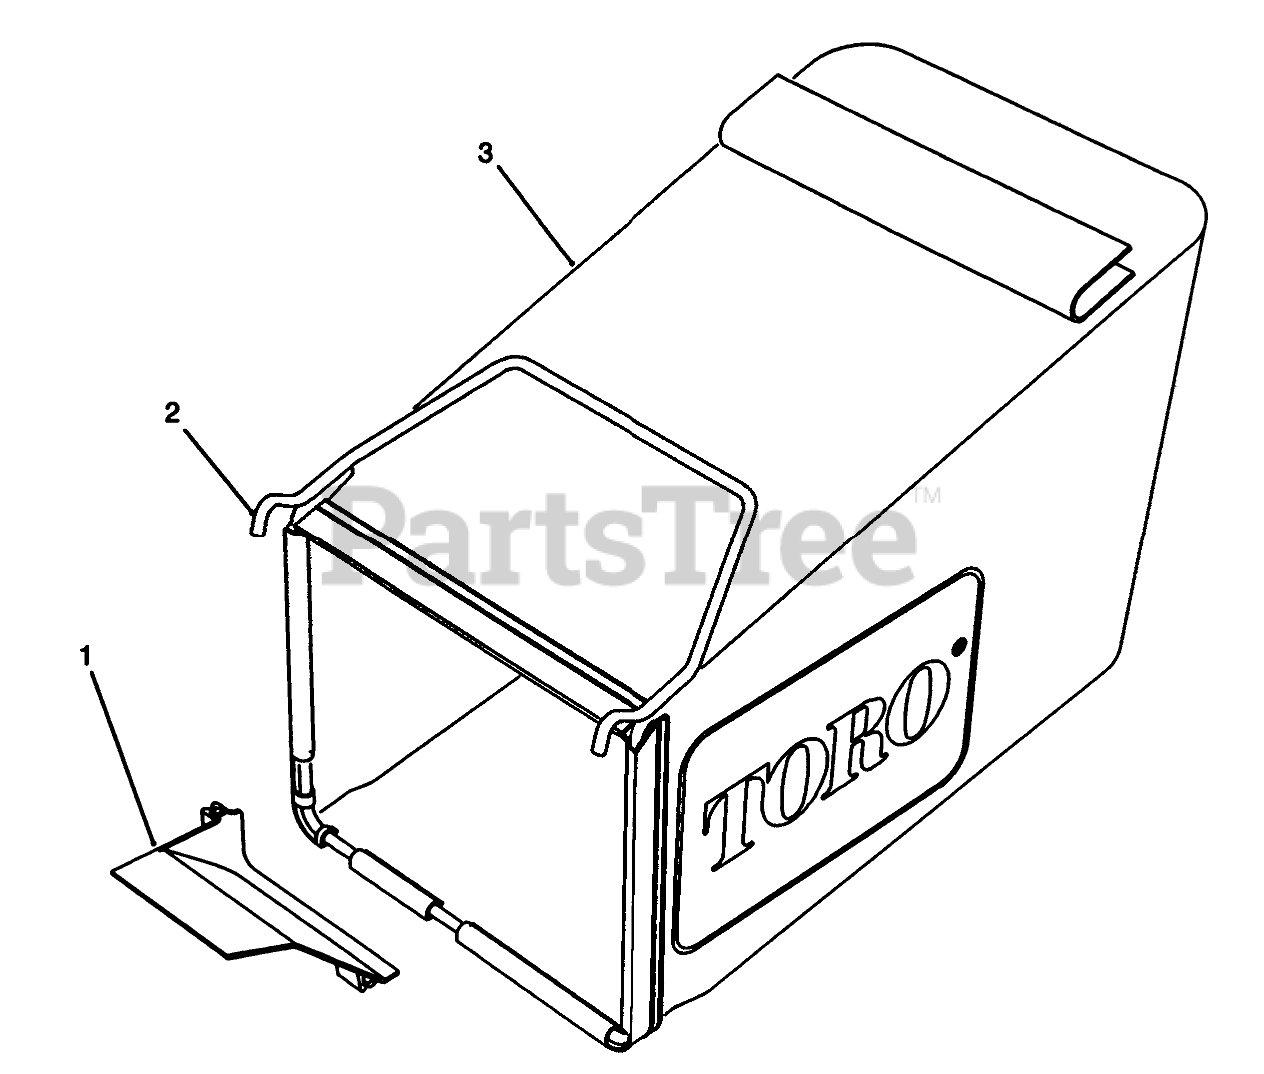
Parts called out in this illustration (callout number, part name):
1	BAG RAMP
2	FRAME WA
3	GRASS BAG REAR EMPTY
